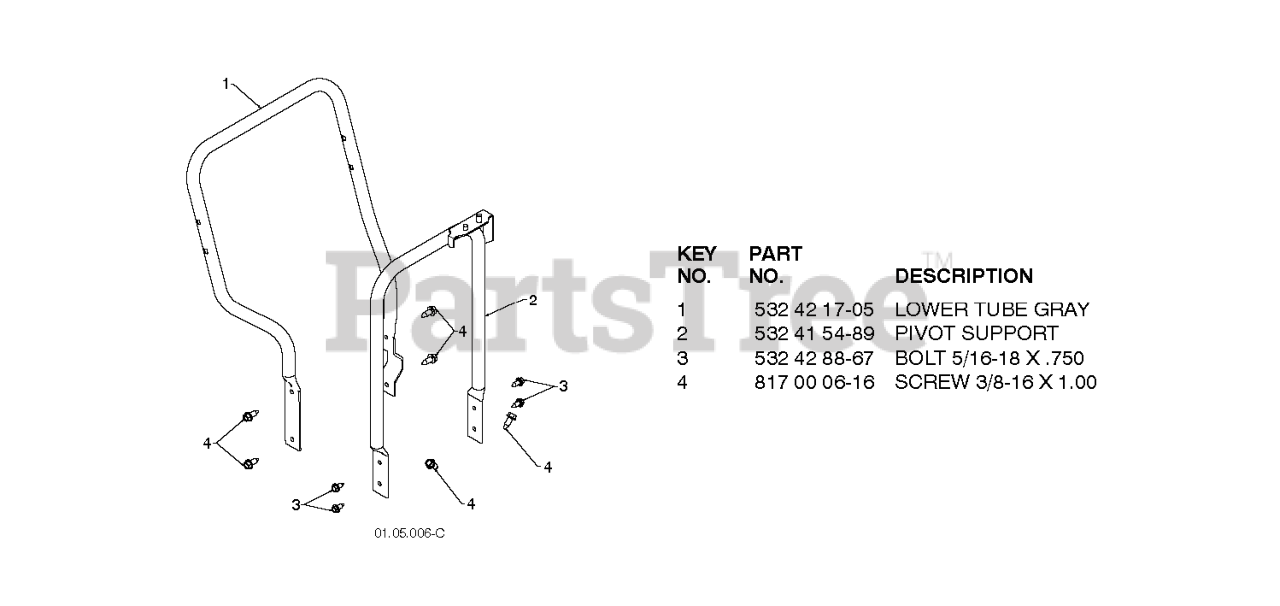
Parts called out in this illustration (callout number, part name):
1	TUBE.LOWER.HANDLE.SNOW.GRAY
2	SUPPORT.PIVOT.WELD
3	BOLT.HEX.HD.WASHER.5/16-18X.75
4	SCREW 3/8-16X1
